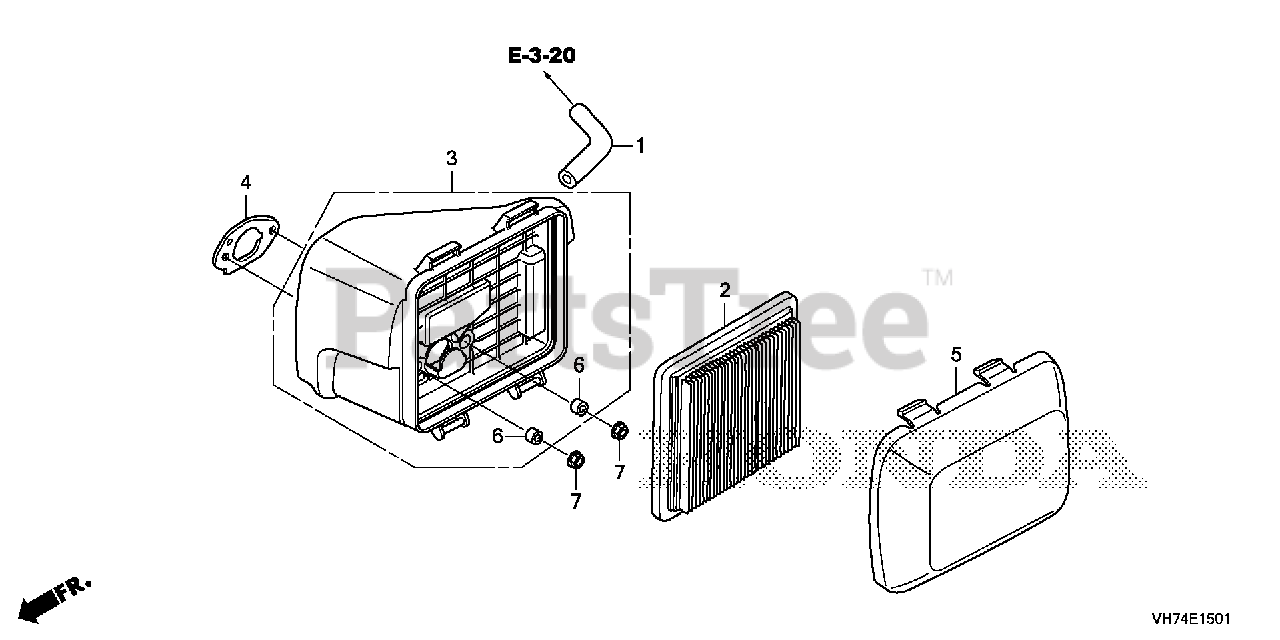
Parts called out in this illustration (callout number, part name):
1	TUBE, BREATHER
2	ELEMENT, AIR CLEANER (WIX FILTERS)
3	HOUSING, AIR CLEANER
4	GASKET, AIR CLEANER
5	COVER, AIR CLEANER
6	COLLAR, AIR CLEANER
7	NUT, FLANGE (6MM)
